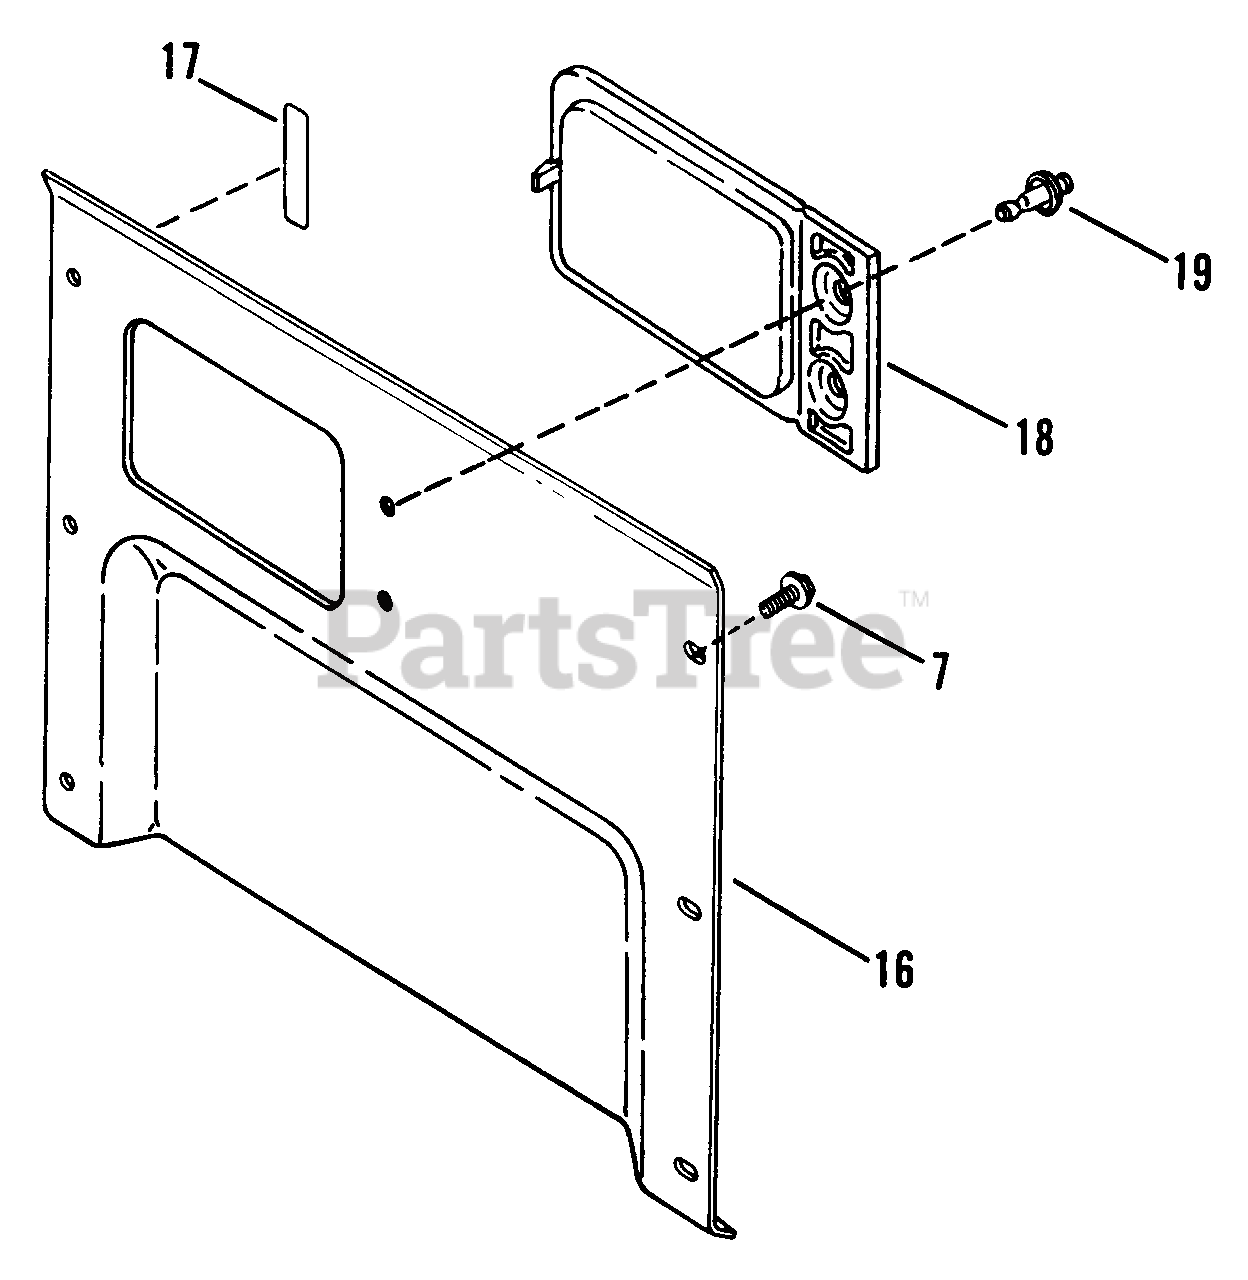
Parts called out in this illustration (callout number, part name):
7	SCREW, 5/16-18x5/8" Self-Tapping
16	COVER, Rear
17	DECAL, Roll
18	COVER, Transmission Oil Access (No longer available)
19	SCREW, Expansion
